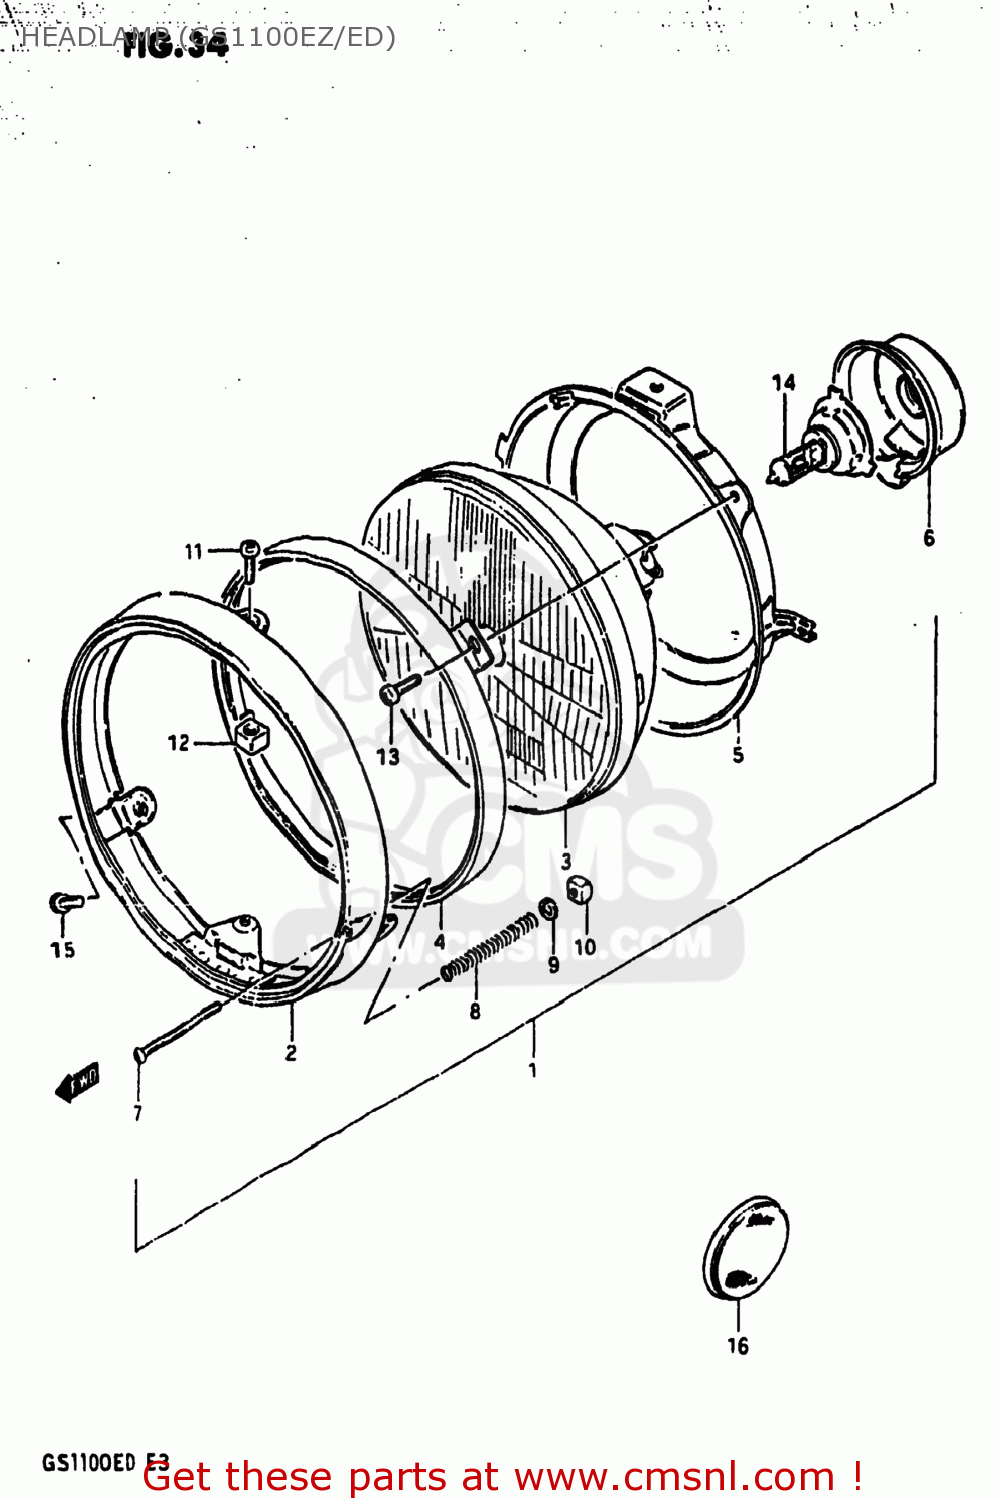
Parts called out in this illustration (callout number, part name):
1	HEADLAMP ASSEMBLY
2	RIM
3	LAMP UNIT
4	RETAINER
5	RING,MOUNTING
6	COVER,HEADLAMP SOCKET
7	SCREW
8	SPRING,HEADLAMP ADJUST
9	WASHER
10	NUT
11	SCREW
12	NUT
13	SCREW
14	BULB(12V60/55W,H4)
15	SCREW(5X12)
16	REFLEX REFLECTOR,RR
